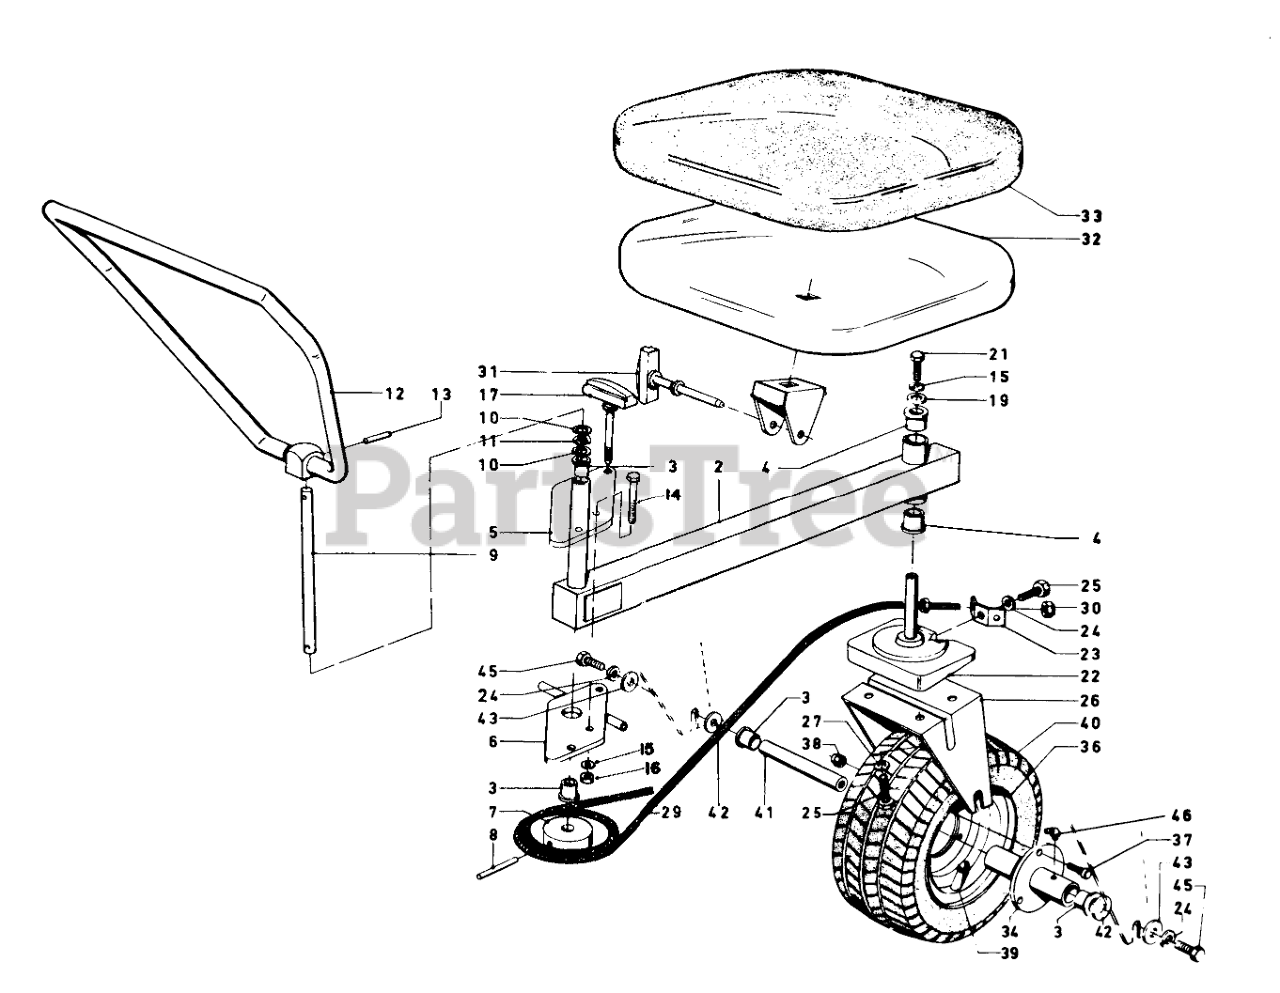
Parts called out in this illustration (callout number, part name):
2	Rear Frame (Incl. Ref. #3 & 4)
3	3/4IDX1LG FLANGE BSHG
4	FLANGE BUSHING
5	Plate, Upper Hinge
6	Plate, Lower Hinge
7	FRT STRG PULLEY RO
9	STEERING SHAFT
10	WASHER-THRUST
11	3/4 SPRING WASHER
12	STEERING HANDLE ASM
13	PIN-ROLL, SLOTTED
14	SCREW-HH
15	WASHER-LOCK
16	NUT-HEX
17	STUD & HANDLE ASM
19	WASHER
21	SCREW-HH
22	PVT CSTR/SFT WARO
23	CABLE BRACKET R
24	WASHER-LOCK
25	SCREW-HH
26	Wheel Fork
27	WASHER-LOCK
29	STRG SWAGED CABLE ASM
30	NUT-LOCK
31	Handle Assembly
32	Seat Assembly
33	SEAT PAD
34	Hub (Incl. Ref. #3)
36	Wheel Disc Assy.
37	DRIVE STUD
38	LUG NUT
39	STEM-VALVE
40	Tire
41	Shaft
42	THRUST WASHER
43	WASHER-FLAT
45	SCREW-HH
46	FITTING-LUBE, 45 DEG
